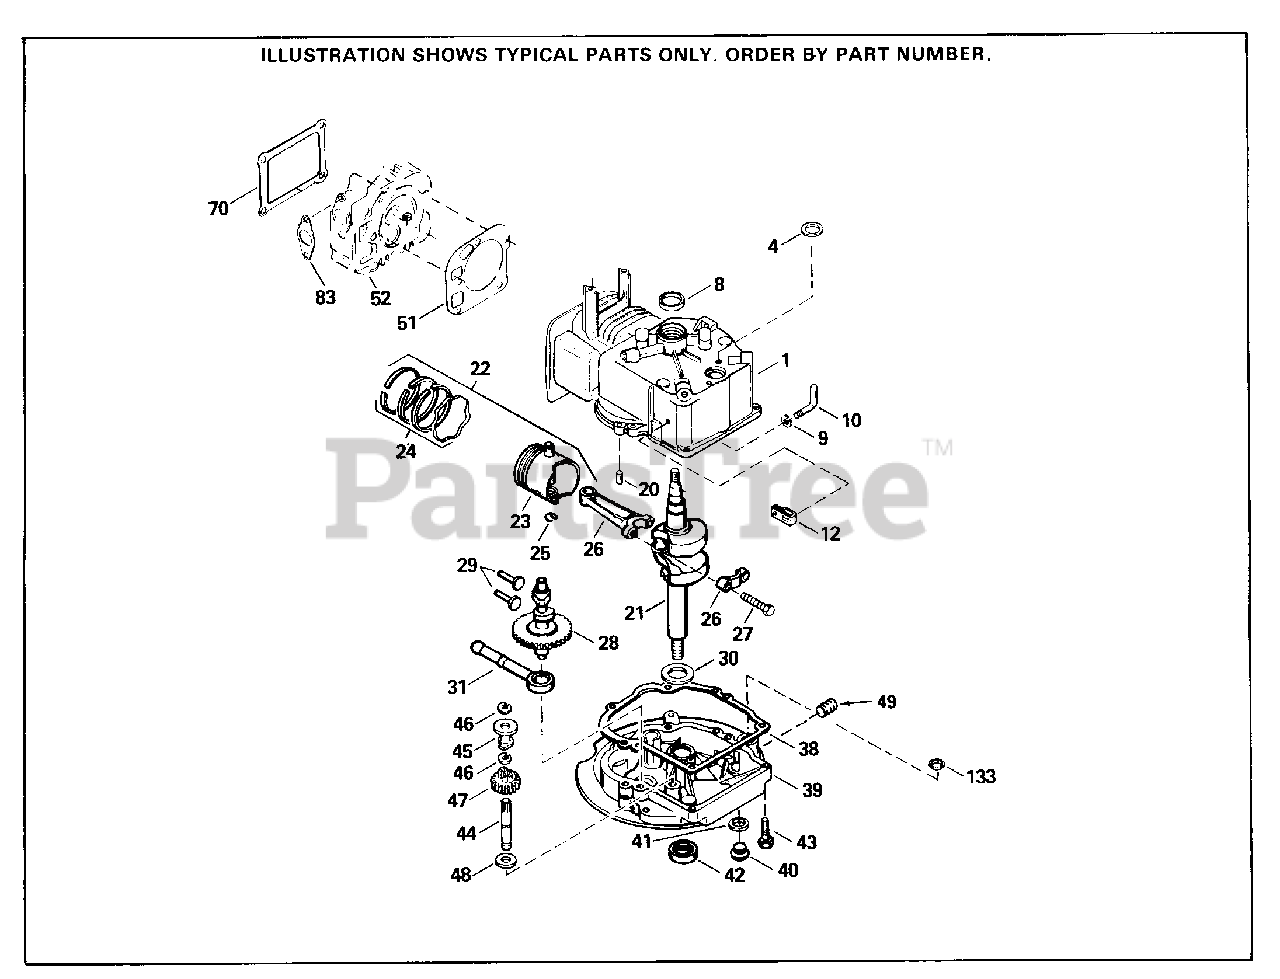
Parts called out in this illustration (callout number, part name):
1	"Cylinder (Incl. 8 & 20)
4	Gasket, Breather
8	Seal, Oil
9	Flat Washer
10	Rod, Governor (Incl. 9)
12	Clamp, Governor lever
20	Dowel Pin
21	Crankshaft
22	Piston, Pin & Ring Set (.020" OS)
22	Piston, Pin & Ring Set (Std.)
22	Piston, Pin & Ring Set (.010" OS)
23	Piston & Pin Ass'y. (Std.) (Incl. 25)
23	Piston & Pin Ass'y. (.010" OS) Incl. 25
23	Piston & Pin Ass'y. (.020" OS) Incl. 25
24	Ring Set (Std.)
24	Ring Set (.010" OS)
24	Ring Set (.020" OS)
25	Piston Pin Retaining Ring
26	Rod Assy., Connecting (Incl. 27)
27	Bolt, Connecting rod
28	Camshaft (MCR)
29	Valve Lifter
30	Washer, Thrust
31	Oil Pump Ass'y.
38	Mounting Flange Gasket
39	Mounting Flange (Incl. 40, 42 & 44)
40	Plug, Oil drain
42	Oil Seal
43	Screw, 1/4-20 x 1-1/4"
44	Shaft, Governor
45	Spool, Governor
46	Retaining Ring
47	Gear Assy., Governor (Incl. 48)
48	Washer, Flat
51	Gasket, Cylinder head
52	Cylinder Head Not included with short block
70	Rocker Arm Cover Gasket
83	Gasket, Intake pipe
133	Gasket, Fill tube
